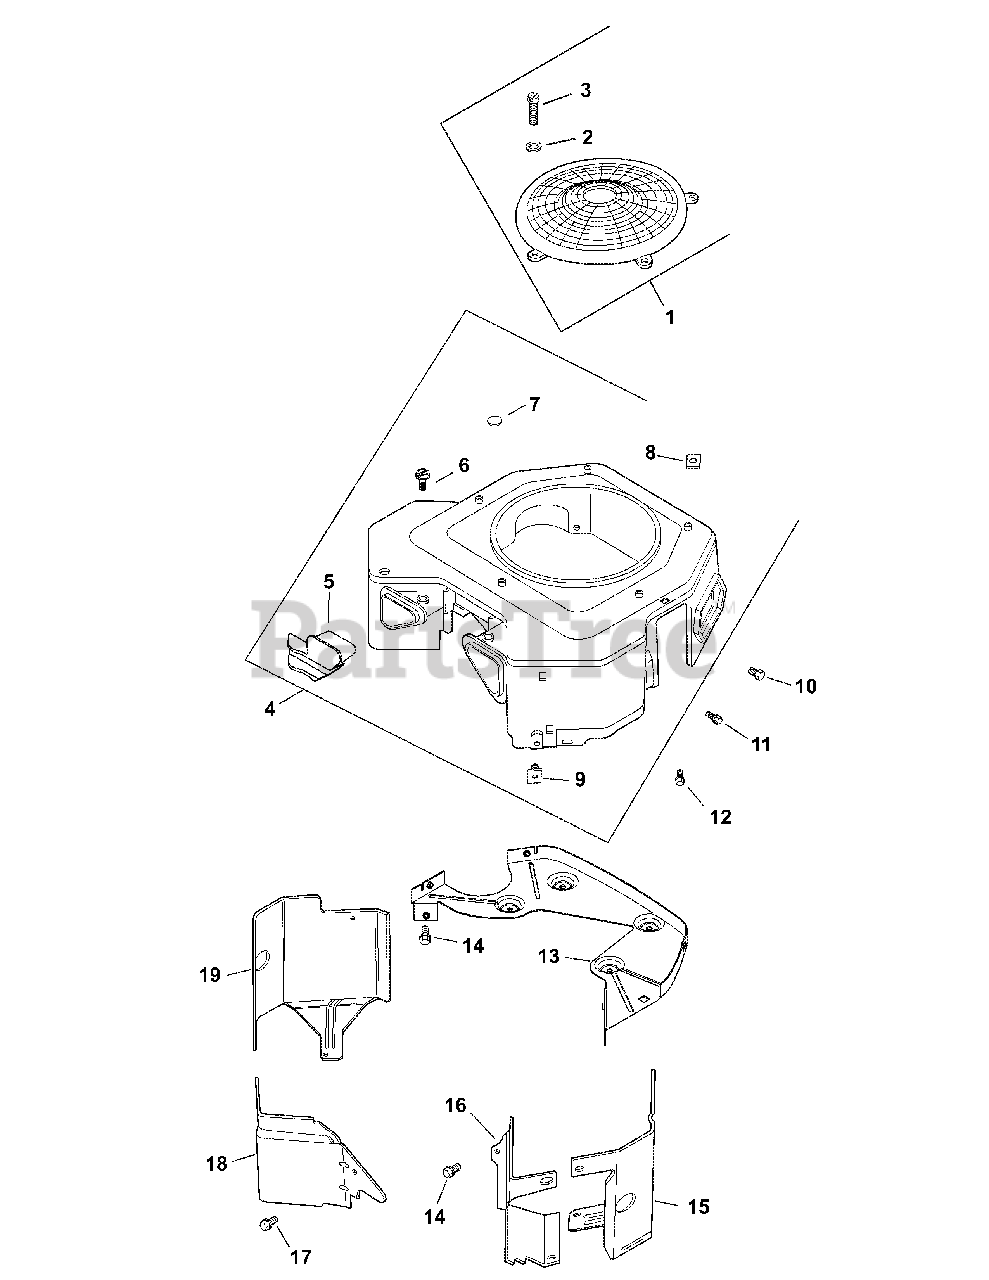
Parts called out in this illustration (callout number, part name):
1	Kit, Fixed Guard
2	Washer, Flat 7/32
3	Screw, LBD SCKT Pan M5x0.8x10
4	Kit, Blower Housing Assembly
5	Cover, Blower Housing
6	Screw, Wsh Hd Tap #8-18 x 1/2"
7	Plug, Button 9/16
10	Screw, FLG THD FRM M5 x .8 x 16
11	Screw, FLG THD FRM M5 x .8 x 16
12	Screw, FLG THD FRM M5 x .8 x 20
13	Kit, Backing Plate
14	Screw, FLG THD FRM M6 x 1.0 x 16
15	Kit, Cyl Baffle-#2 Side
16	Baffle, Valley-#2 Side
17	Screw, FLG THD FRM M5 x .8 x 10
18	Baffle, Valley #1 Side
19	Kit, Cyl Barrel - #1 Side
